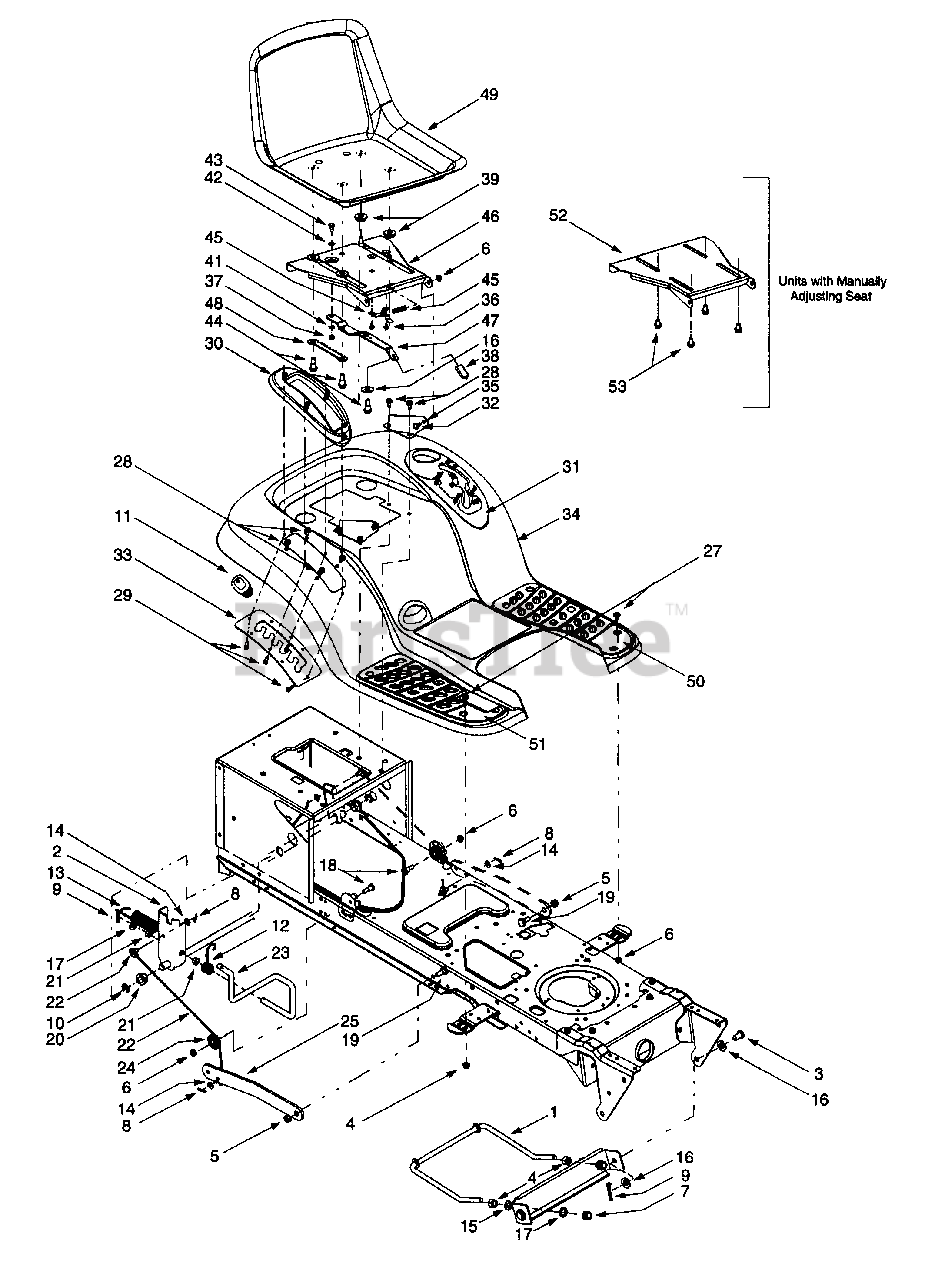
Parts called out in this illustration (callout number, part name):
1	Deck Stabilizer Rod
4	Hex Nut, 1/2-13
5	Flange Lock Nut, 3/8-16
6	Flange Lock Nut, 5/16-18
7	Hex Nut, 1/2-13
8	Internal Cotter Pin
9	Cotter Pin
10	E-ring
11	Handle Grip
12	Torsion Spring
13	Lift-assist Spring, 1.15 x 5.99
14	Flat Washer, 5/16
15	Lock Washer, 1/2
16	Flat Washer, .31 x 1.062 x .134
17	Flat Washer, .51 x 1.12 x .06
18	Hex Cap Screw, 5/16-18 x .62
19	Shoulder Screw, .5 x .27, 3/8-16
20	Hex Flange Bearing
21	Snap Flange Bearing
22	Lift Cable, 16.16
23	Lift Handle
24	Roller Pulley
27	Carriage Bolt, 5/16-18 x .62
28	Self Tapping Screw, 5/16-18 x .625
29	Self Tapping Screw, 1/4-15 x .75
30	Lift Lever Cover
31	Shift Lever Cover w/Cup Holder
32	Shoulder Screw, .437 x 1.62
36	Screw, #10-16 x .375
37	Hex Flange Lock Nut, 1/4-20
38	Seat Adjuster Grip
39	Spacer
41	Spring Washer, .265 x .562 x .025
42	Flat Washer, .344 x .62 x .03
43	Shoulder Screw, .340 x .285, 1/4-20
44	Shoulder Screw, .50 x .50, 3/8-16
45	Seat Stop
48	Seat Adjustment Selector
49	Seat, Medium Back
50	LH Foot Pad
51	RH Foot Pad
